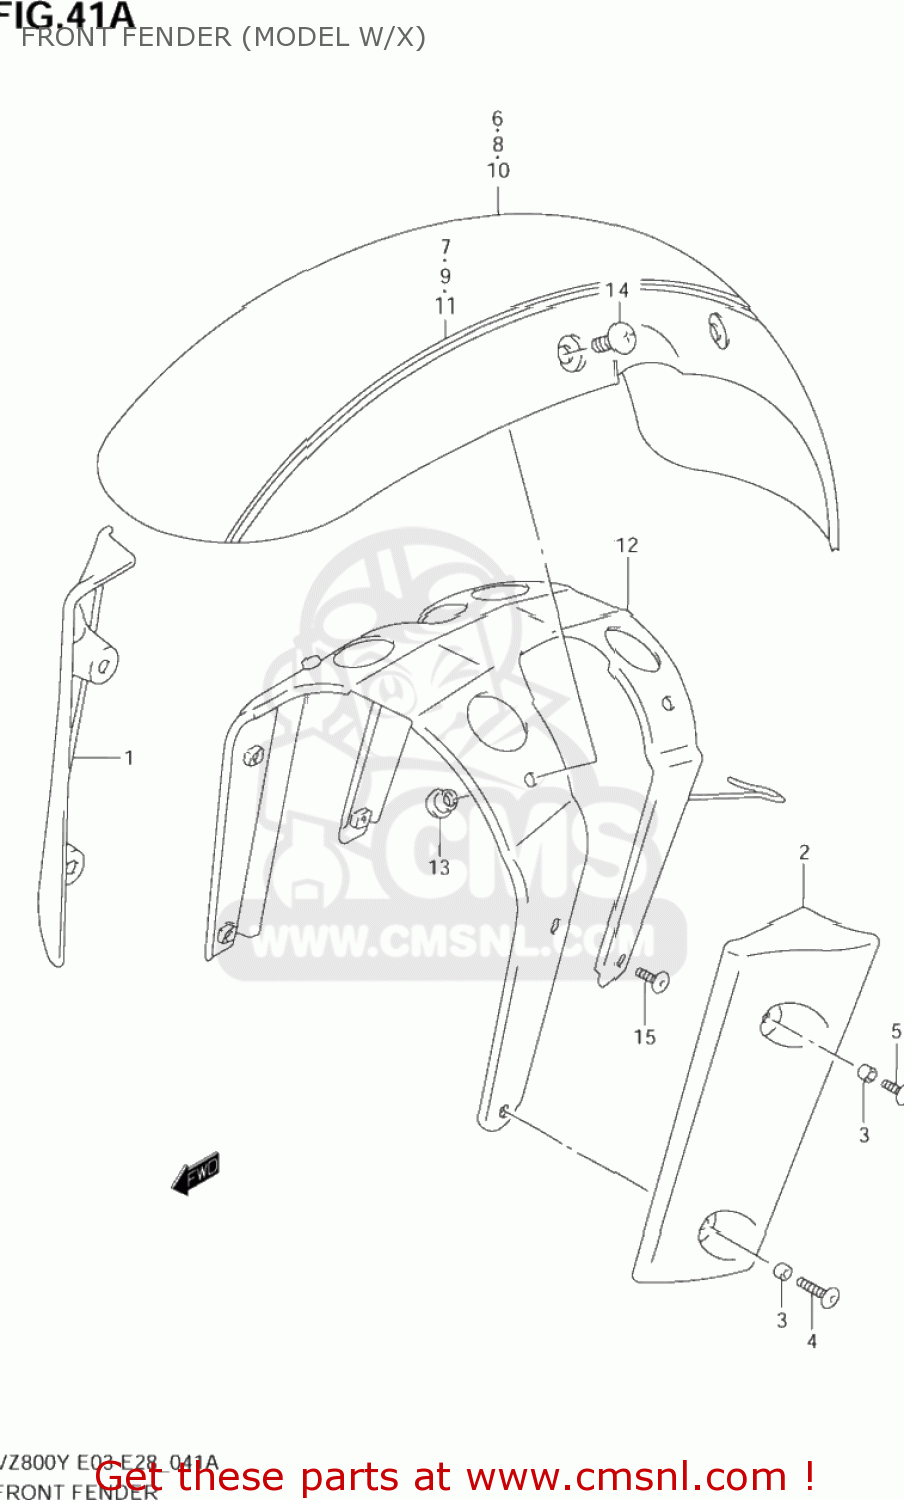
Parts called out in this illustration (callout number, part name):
1	COVER,FR FORK SIDE,R
2	COVER,FR FORK SIDE,L
3	SPACER(6.1X8X3.5)
4	SCREW(6X20)
5	SCREW(6X12)
6	FENDER COMP,FRONT
7	TAPE SET,FRONT FENDER
8	FENDER,FRONT
9	TAPE SET,FR FENDER
10	FENDER COMP,FRONT
11	TAPE SET,FR FENDER
12	BRACE,FR FENDER
13	NUT
14	SCREW(6X12)
15	SCREW(6X16)
